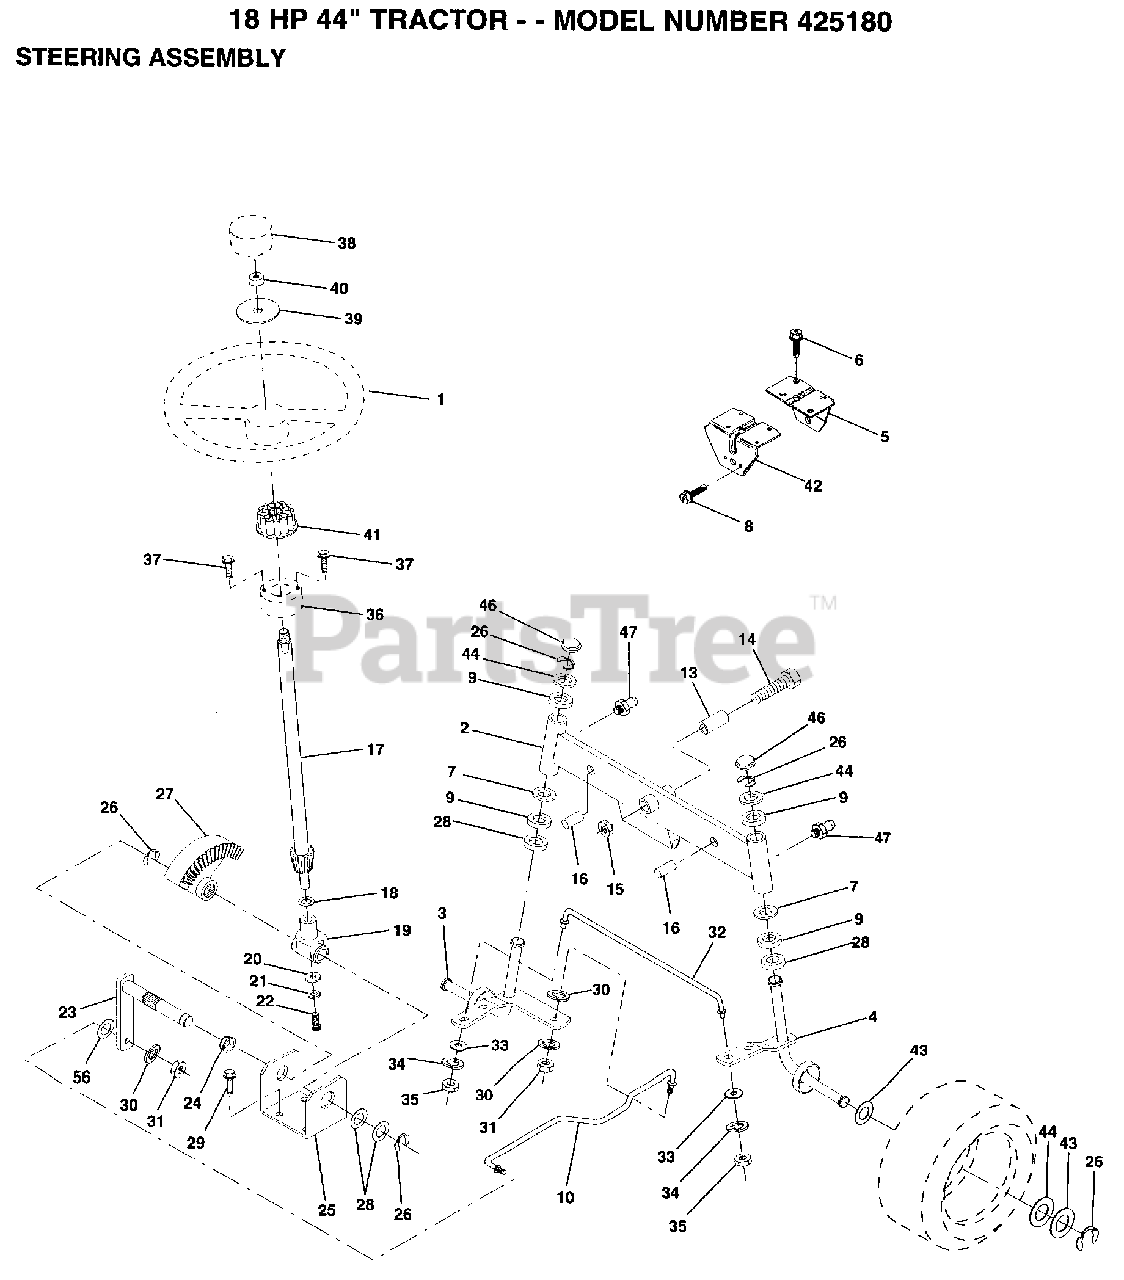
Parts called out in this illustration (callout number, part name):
1	WHEEL STR AYP BLK
2	AXLE ASM FRONT
5	SUPPORT.SADDLE.FT
6	SCREW SPECIAL
7	WASHER
8	SCREW LT
9	COL. SRTG. BEAR.
13	BEARING
14	BOLT LT
15	"NUT-LOC,FLANGE LT"
16	AXLE PIN
18	THRUST WASHER
19	SUPPORT.SHAFT
21	LOCKWASHER
22	"SCREW,SPECIAL"
24	NYLINER T
25	"BRKT,STEERING"
26	RING
27	GEAR SECTOR
28	WASHER .T
29	SCREW
30	LOCKWASHER
32	TIE ROD
33	WASHER M
34	LOCKWASHER
35	NUT.LOCK.5/16-24
38	CAP STEER AYP
39	WASHER
41	ADAPTER LT
42	SUPPORT-SADDL T
43	WASHER
44	WASHER
46	CAP
47	ZERK M
56	WASHER 13/32 X 3/4 X 10 GA
